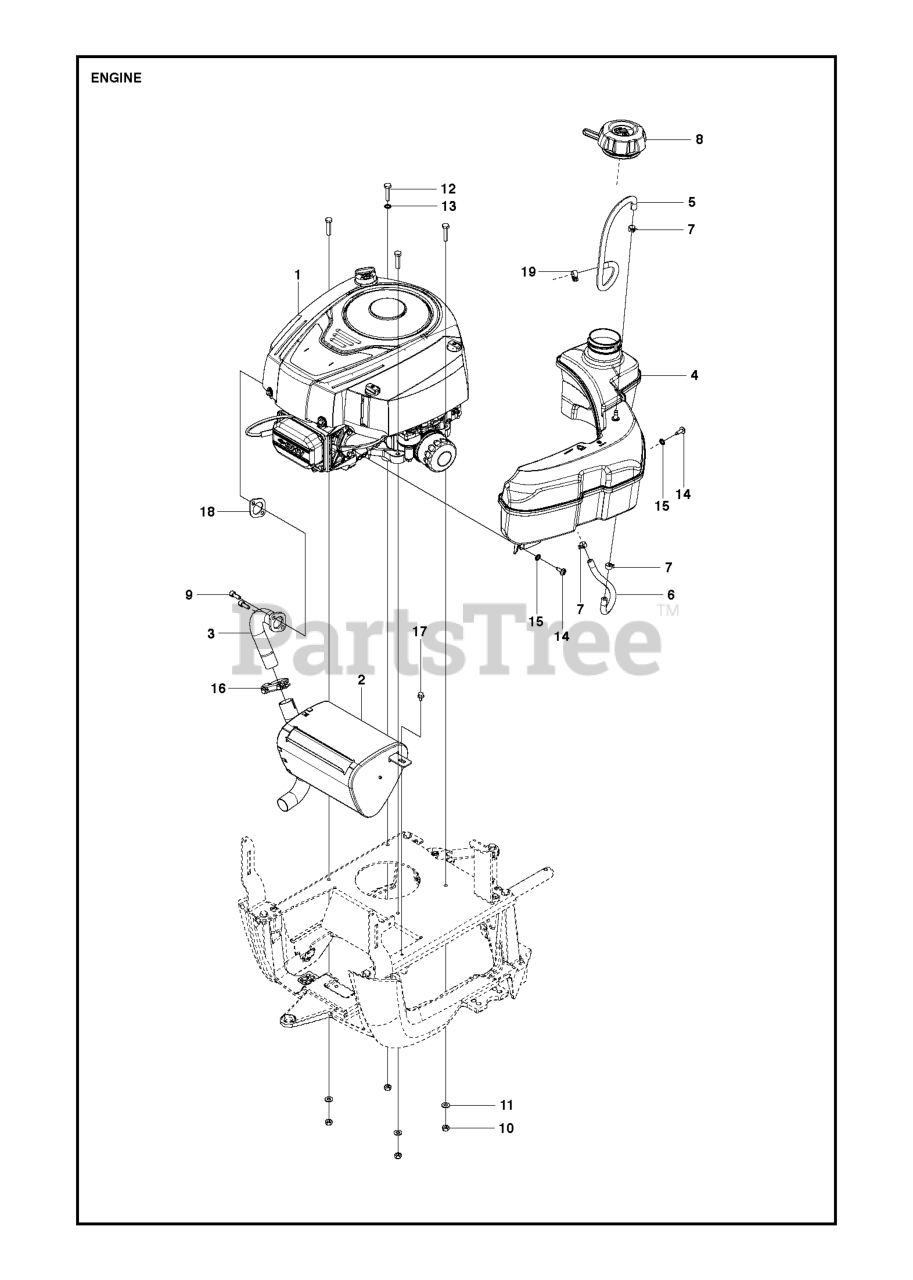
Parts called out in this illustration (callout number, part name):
2	MUFFLER ASSY
8	CAP.ASM.FL.RITCH.3"E10.SYM.498
10	LOCKNUT M8
11	WASHER BRB 8.4X17
16	CLAMP
19	HOSE CLAMP
